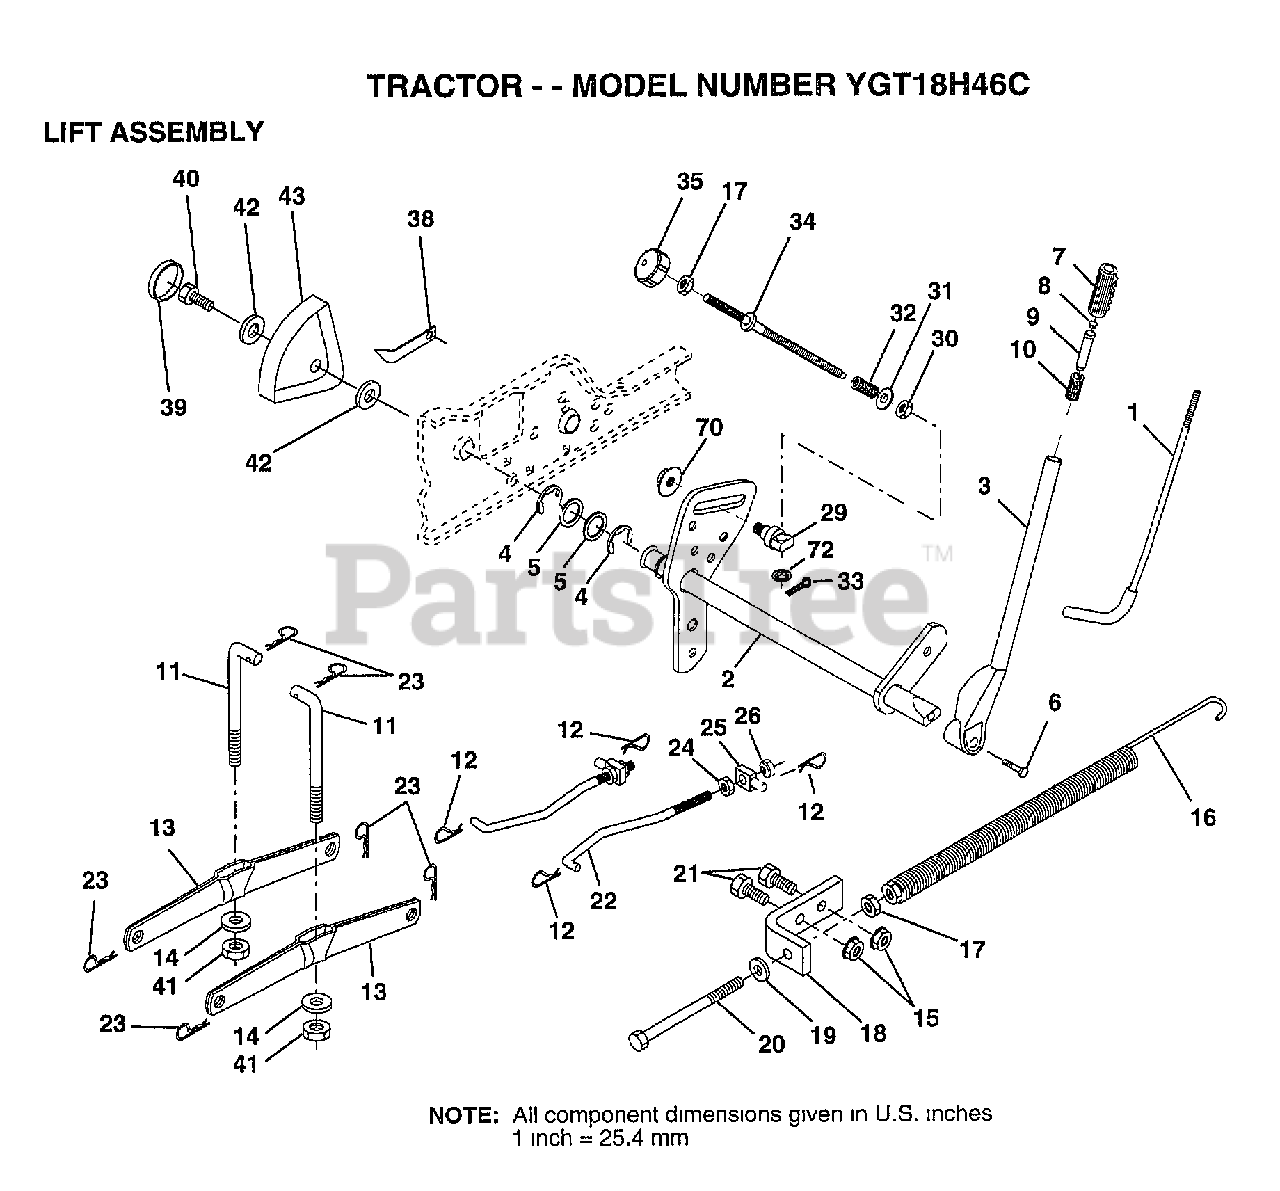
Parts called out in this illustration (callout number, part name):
1	LEVER ROD LT
2	SHAFT.ASM.LIFT.VGT
3	LEVER.ASM.LIFT.RH
4	E-RING
5	WASHER
6	"BOLT,HEX"
7	GRIP HANDLE
10	SPRING T
11	LINK.LIFT.MWR.VGT
12	RETAINER SPRING
13	ARM SUSP REAR
14	BEARING PVT LH
17	NUT
18	BRACKET SPRING AS
19	WASHER
20	BOLT-ADJ SPRING T
21	BOLT
22	LINK.FRONT
24	NUT
25	TRUNION
26	NUT LTV
29	TRUNNION
30	NUT T
31	WASHER
32	SPRING.COMP.INF.H
34	ROD.ADJ.LIFT
35	KNOB INF 3/8-16
38	POINTER-INDICAT
39	"PLUG,HOLE"
40	SCREW
41	NUT.CROWNLOCK.3/8
42	WASHER
43	HEIGHT INDICATOR
70	NUT.HXFLG.LOCK.
72	NUT PUSH M
